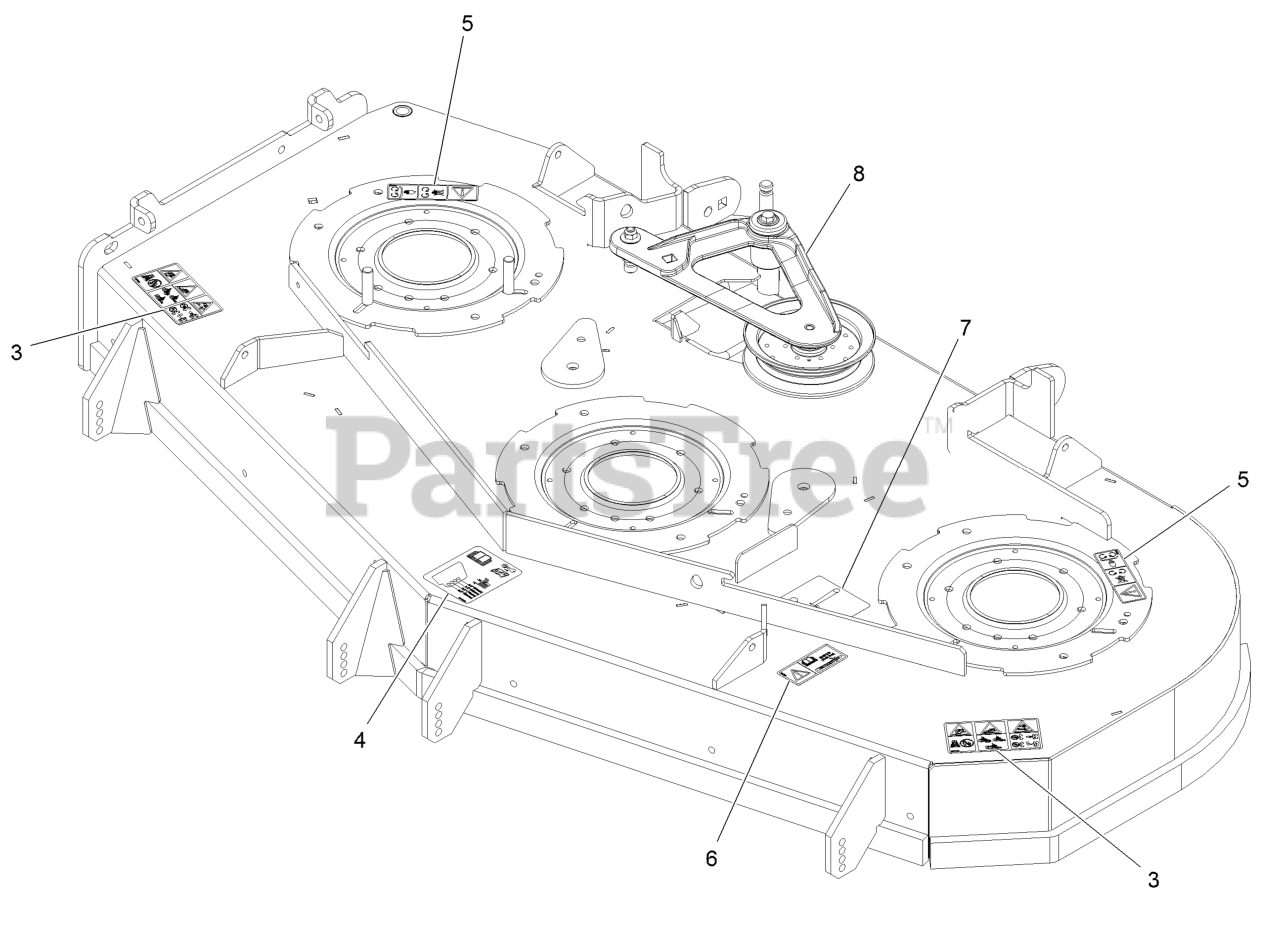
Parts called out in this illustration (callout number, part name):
3	DECAL-DANGER THROWN OBJECTS
4	DECAL-ROLLER, ANTI-SCALP
5	DECAL-COVER, MISSING
6	DECAL-BOLT TORQUE
7	DECAL-BELT ROUTING
8	DECK IDLER ASM
